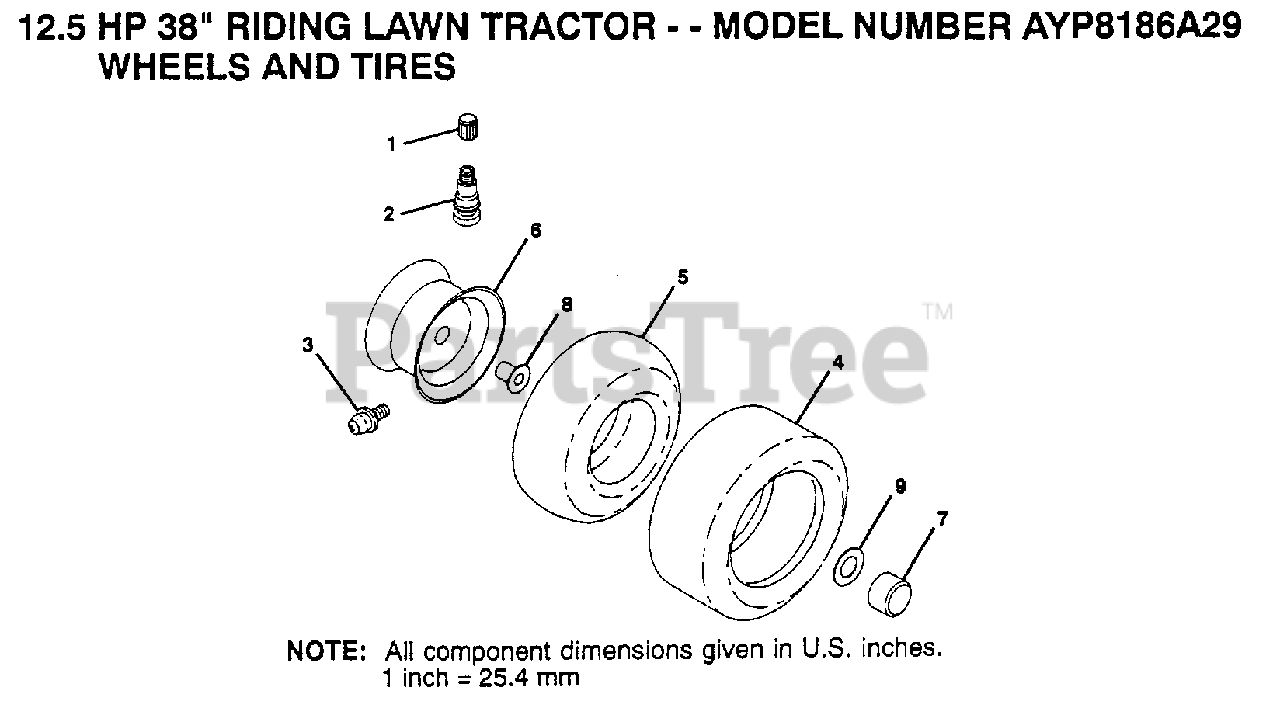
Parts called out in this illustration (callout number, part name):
1	VALVE CAP
2	VALVE STEM LT
3	FITTING LT
5	TUBE.5.3/4.5/6
5	TUBE.23X8/10-12
7	HUB CAP
8	"FLANGE, BEARING"
9	WASHER
